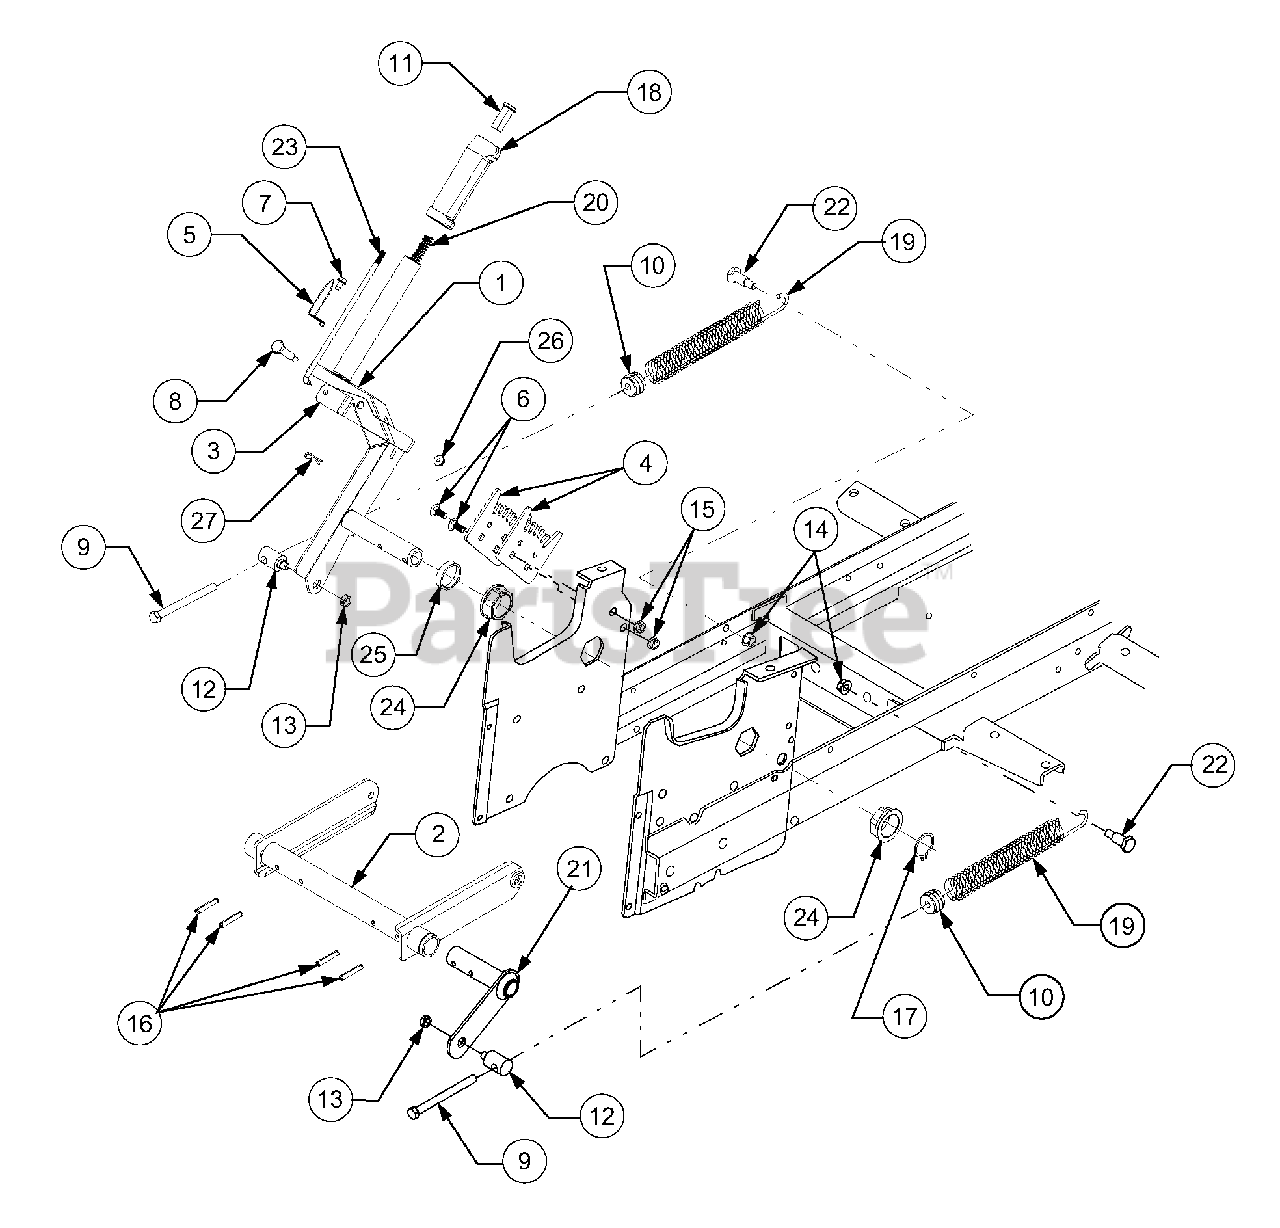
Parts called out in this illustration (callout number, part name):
1	Handle Assembly, Lift
2	Shaft Assembly, Lift
4	Bracket, Lift Index
5	Indicator, Lift Height
6	Bolt, Carriage, 5/16-18 x .75
7	Screw, Hex Wash Tapp, 1/4 x .5
8	Screw, Shoulder, .374 x 1.375
9	Screw, Hex Cap, 3/8-16 x 4.25 GR5
10	Insert, Spring
11	Button, Handle
12	Ferrule, Adjustment
13	Nut, Hex Center Lock, Jam, 3/8-24
14	Nut, Hex Flanged Lock, 3/8-16
15	Nut, Hex Flanged Top Lock, 5/16-18
16	Pin, Spiral Spring, 1/4 Dia x 1.5
17	Ring, Snap, 1.25 Dia Shaft
18	Grip, Lift Handle
19	Spring, Extension
20	Spring, Compression
21	Arm, Lift Assist RH
22	Bolt, Shoulder
23	Rod, Index
24	Bearing, Hex Flange, 1.25 ID
25	Spacer, 1.28 ID x 1.5 OD x .335 Lg
26	Nut, Hex Flange Lock, 1/4-20
27	Pin, Internal Cotter
